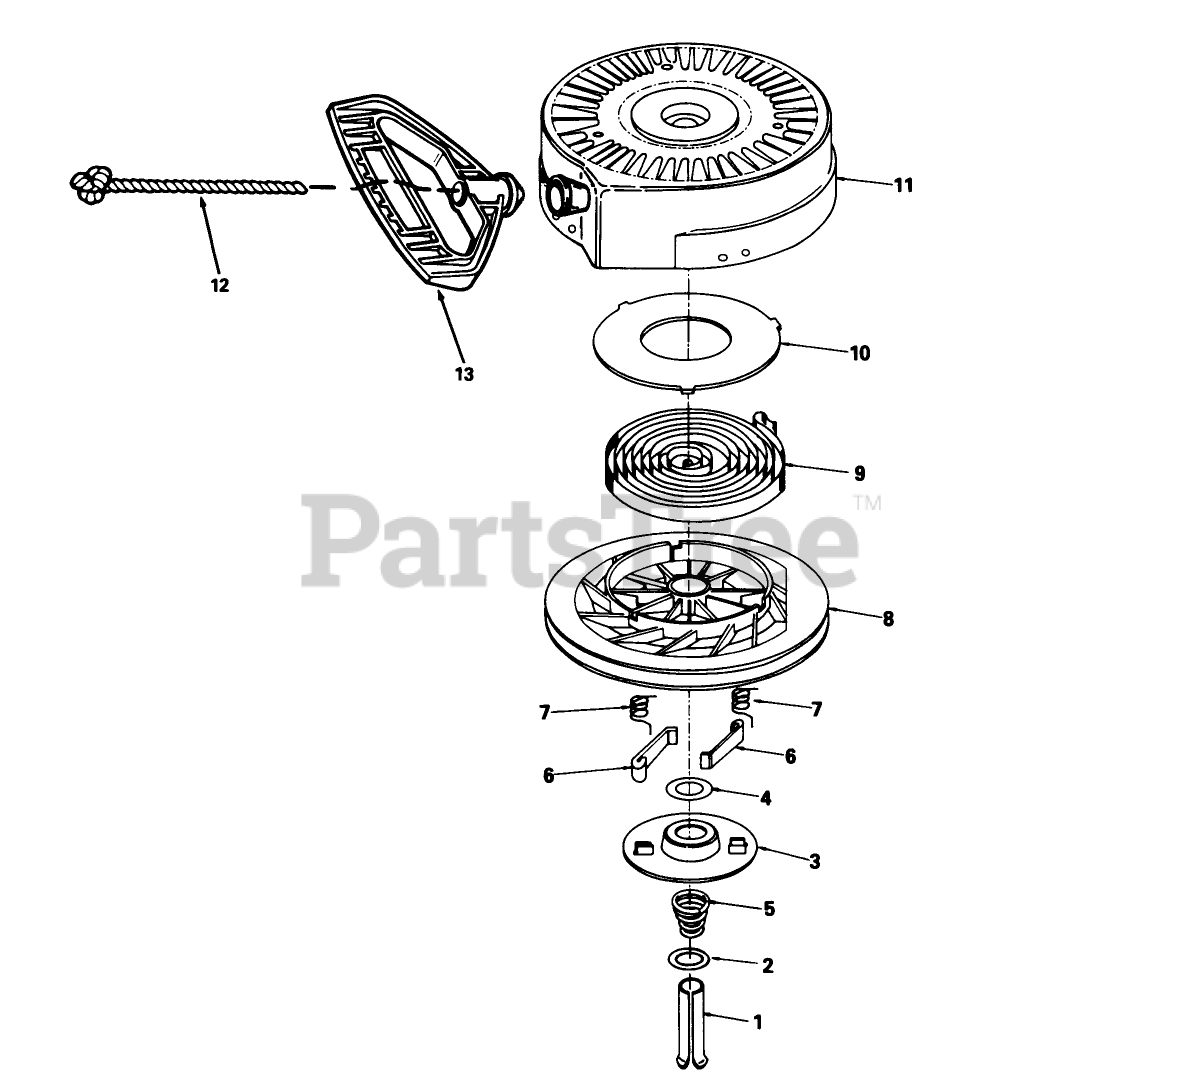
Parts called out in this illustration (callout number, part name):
1	Pin, Spring (Incl. Ref. #7)
2	Washer
3	Retainer
4	Washer
5	Brake Spring
6	Dog-Starter
7	Spring-Dog
8	Pulley
9	Rewind Spring
10	Cover-Spring
11	Housing Assembly
12	Rope-Starter (98 cut to length)
13	Handle-Starter, Mitten Grip
